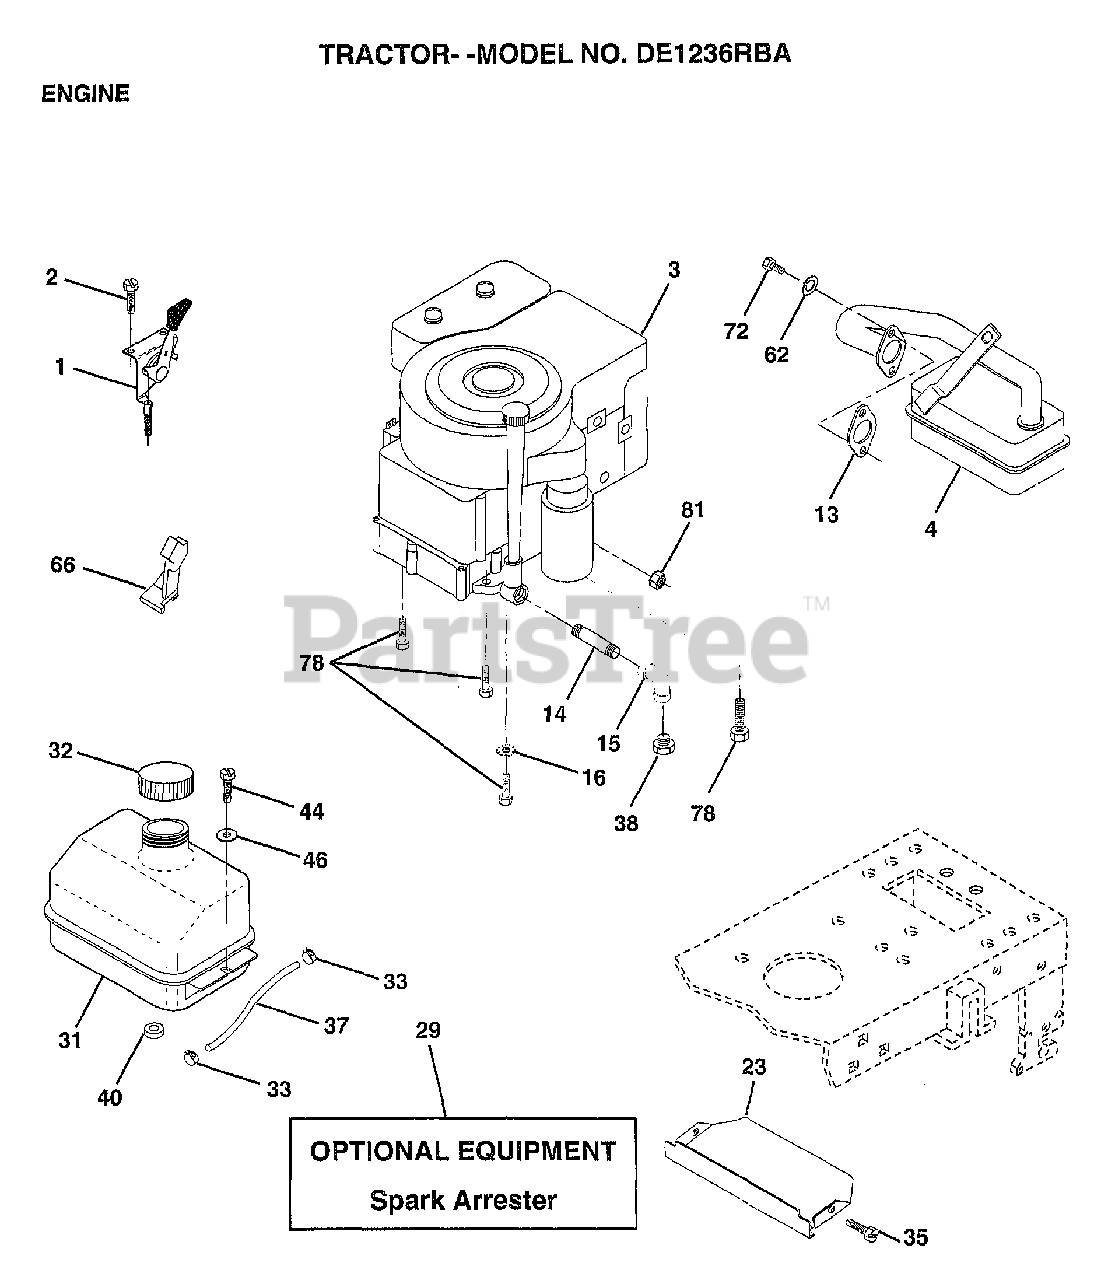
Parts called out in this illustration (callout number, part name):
1	CONTROL.THTL.23.5
2	SCREW LT
4	MUFFLER
14	PIPE NIPPLE
15	ELBOW
16	LOCKWASHER
23	SHIELD.BRN/DBR.GD
31	TANK.FUEL.LT.
32	CAP ASM FUEL
33	HOSE CLAMP
35	SCREW
37	LINE FUEL
44	SCREW HEX CRT
46	WASHER
62	LOCKWASHER
66	"STOP,DASH THROTT"
72	SCREW
78	SCREW
81	NUT
